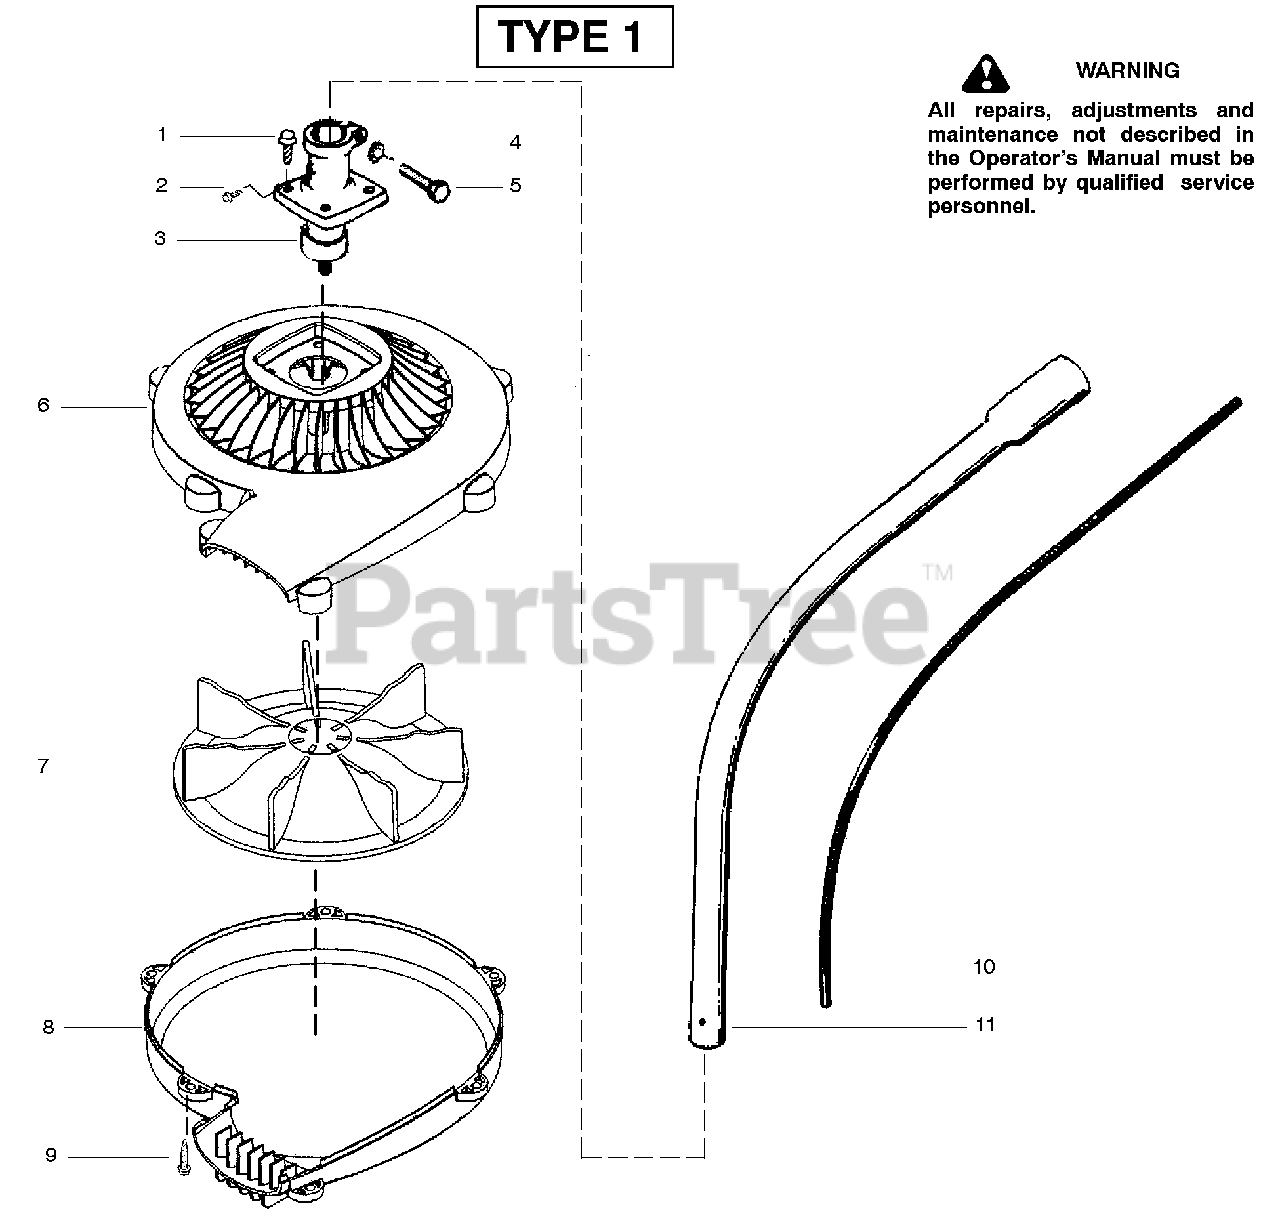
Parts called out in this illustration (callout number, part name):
1	Screw (brg hsg/blwr)
2	Screw-Shaft Alignment
3	Assy-Bearing Hsg.
4	Washer-Lock (star)
6	Blower-Scroll (upper)
8	Blower-Scroll (lower)
10	Flexshaft-Split Boom
11	Assy-Lower Driveshaft
